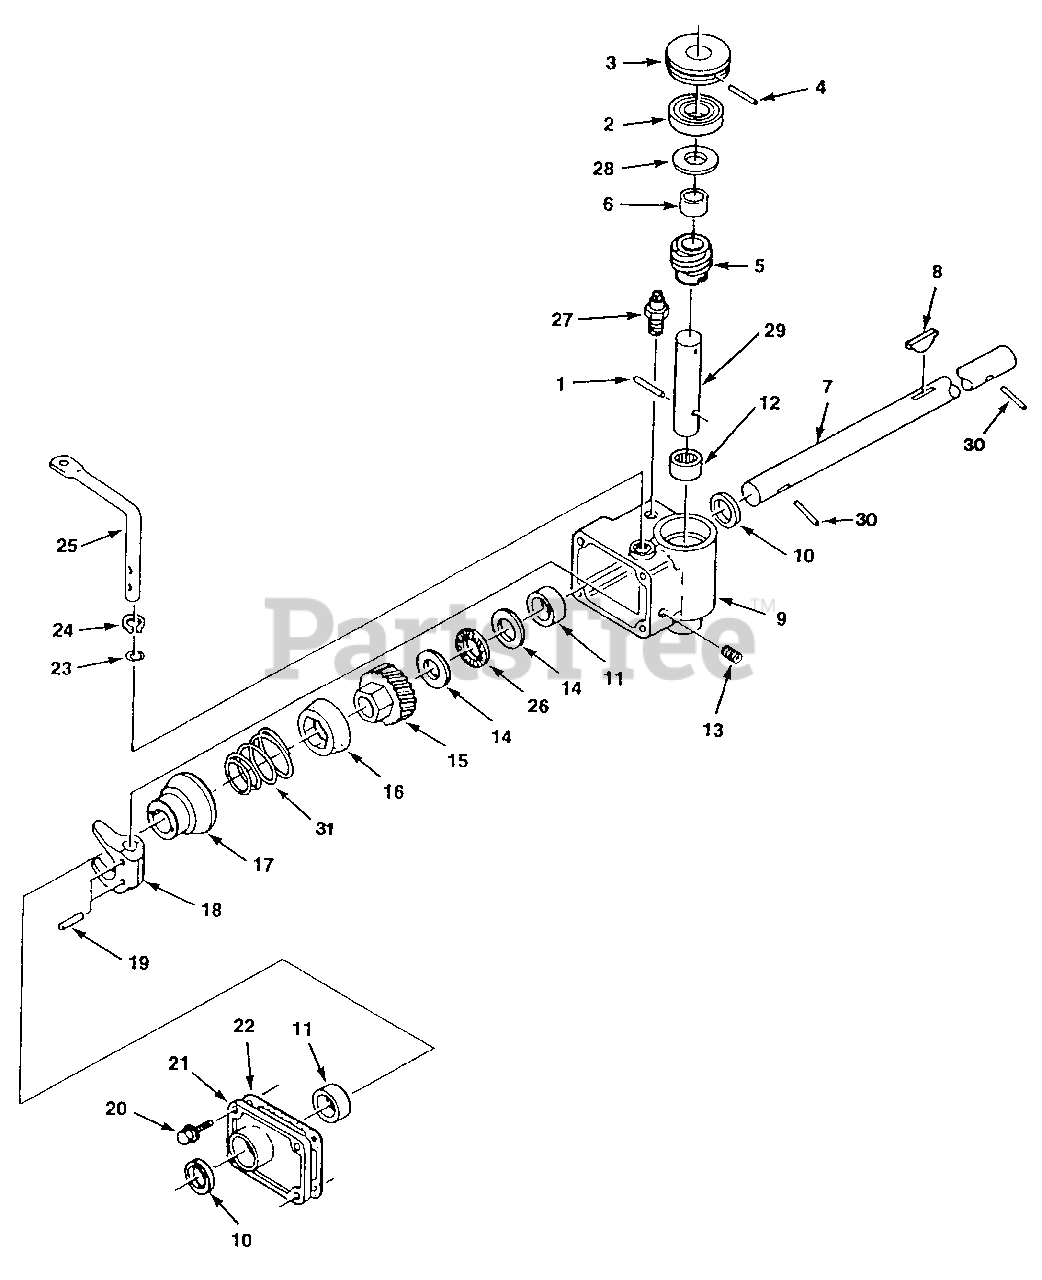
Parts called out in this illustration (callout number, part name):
1	Pin-roll 3/16 x 7/8
2	Bearing - bail
3	Pulley - drive
4	Pin-roll 3/32 x 1- 1/4
5	Worm w/spacer
6	Spacer - worm
7	Shaft - drive
8	Key - Woodruff
9	Housing - gear
11	Bushing - sleeve
12	Bearing - needle
13	Plug - pipe
14	Race - thrust
15	Gear - helical
16	Cone - friction
17	Drum - clutch
18	Fork - shift
19	Pin - groove
20	Screw - hex 1/4-20 x 7/8
21	Cover - gear box
22	Gasket - cover
24	Ring - retainer
25	Lever - shift
26	Bearing - needle
28	Washer - flat
29	Shaft - worm
30	Pin - roll 1/8 x 7/8
31	Spring - clutch
